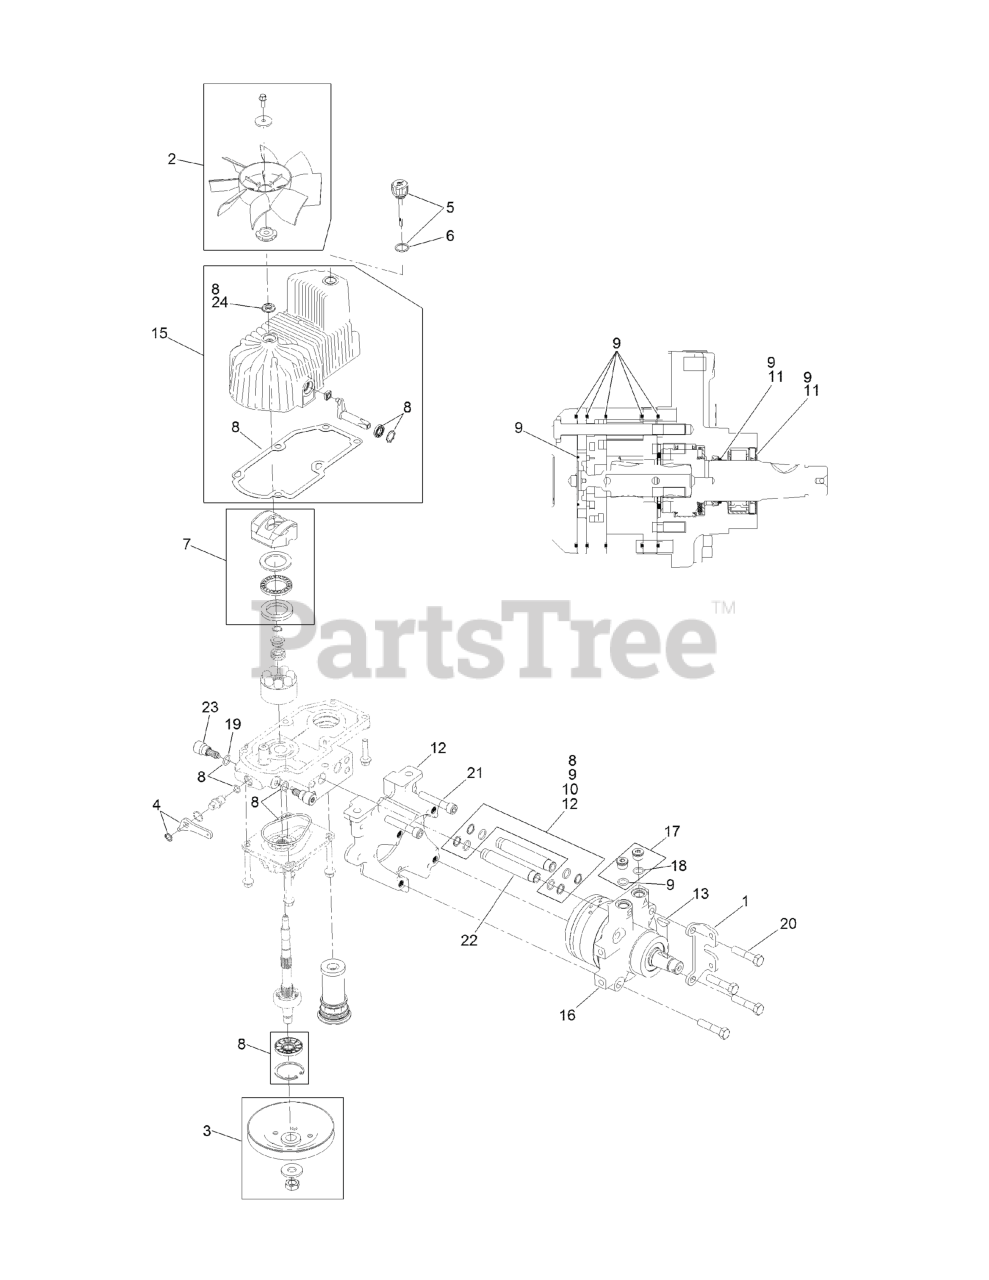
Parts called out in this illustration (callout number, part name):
1	MOUNT-SHOE, HORSE
2	FAN KIT
3	PULLEY KIT
4	HANDLE-BYPASS VALVE, HYDRO
5	DIPSTICK-HYDRO W/GASKET
6	GASKET-DIPSTICK, HYDRO
7	SWASH BLOCK KIT
8	PUMP SEAL KIT
9	MOTOR SEAL KIT
10	TUBE SEAL KIT
11	OUTPUT SHAFT SEAL KIT
12	NOSE CUP-UHT
13	KEY-WOODRUFF
15	HOUSING-HYDRO, RH
16	MOTOR-HYDRAULIC RH 240CC
17	MAGNETIC PLUGS SERVICE KIT
19	O-RING-CHECK VALVE
20	SCREW HH
21	SCREW-HSH
22	HYDRAULIC TUBE KIT
23	SHOCK VALVE, 12CC HYDRO
24	SEAL-FAN DRIVE
25	Kit, Pump Section 12Cc RH
26	KIT, ROTATING GRP 12CC RH
